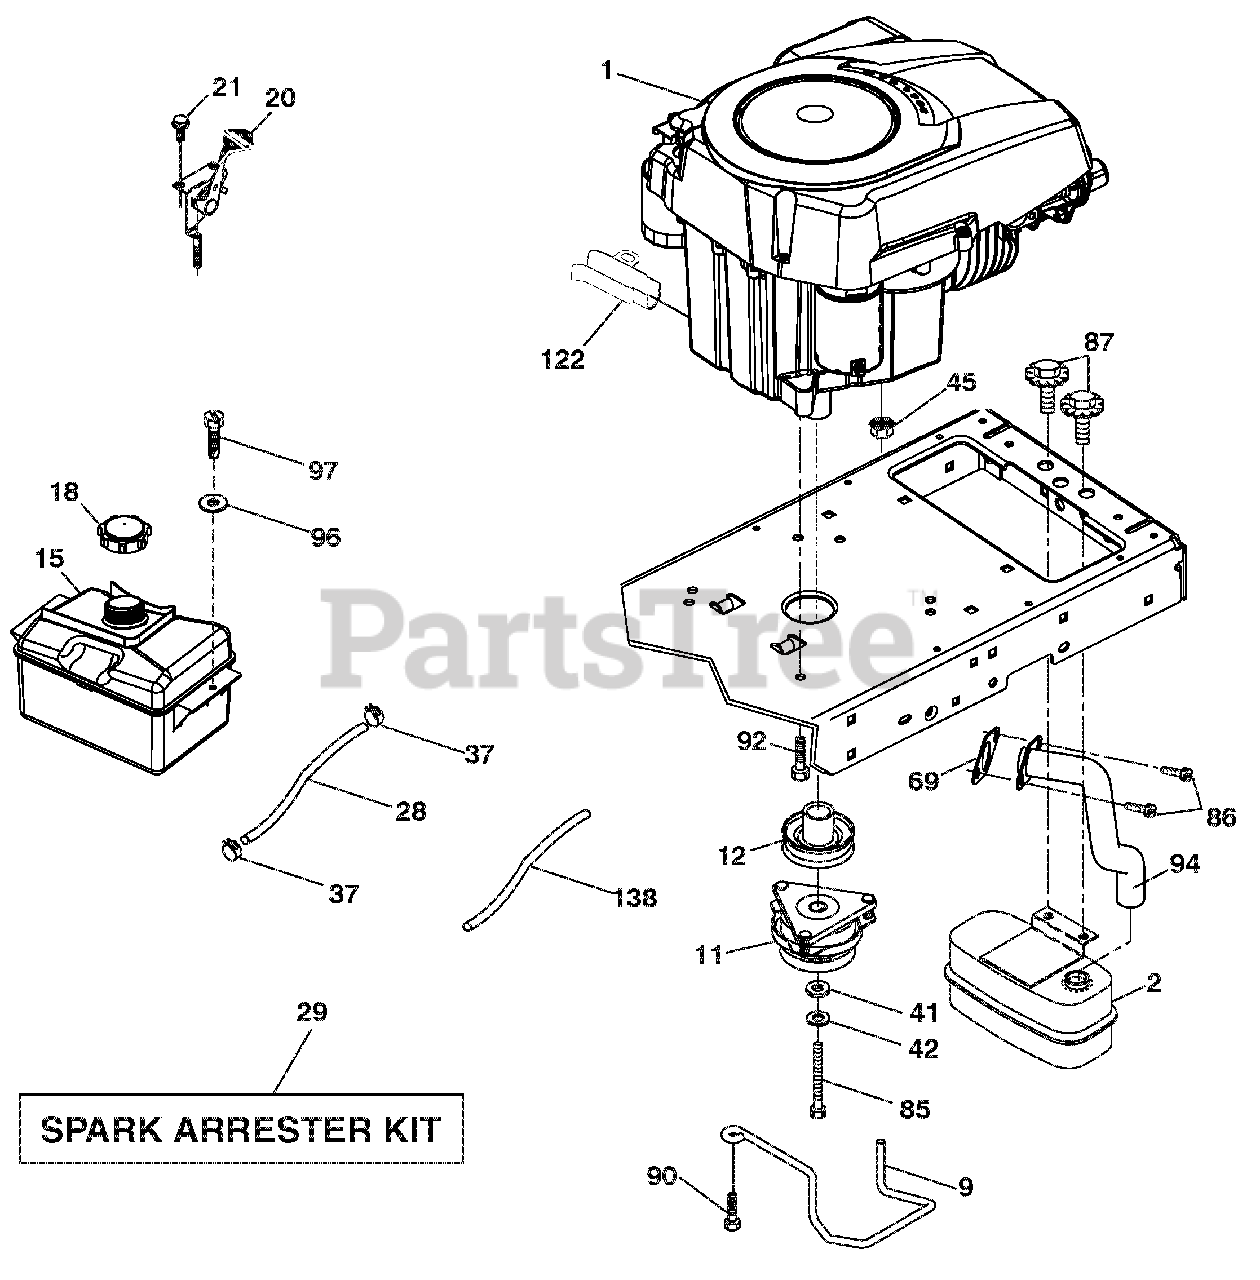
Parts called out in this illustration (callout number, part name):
1	ENGINE KOHL MODEL NO. SV590-3230(445326) (ORDER PARTS FROM ENGINE MANUFACTURER)
2	MUFFLER.SINGLE.CYL.KOHL.COURAG
9	KEEPER.BELT.ENGINE.4.25"NSTG
11	CLUTCH OGURA
12	PULLEY.ENGINE.TUFFTORQE.1"CRK.
15	TANK.FUEL.2.5.GAL.
18	CAP FUEL
20	CONTROL THROTTLE/CHOKE
28	LINE.FUEL.22"FRONT.EMIS.CA.LP
29	KIT.SPARK ARRESTOR(392390 B&S)
37	CLAMP.HOSE.BLK.
41	WASHER.1-1/2 ODX15/32 IDX.250
42	WASHER.LOCK.HVY HLCL.SPR.7/16
45	Nut, Keps Hex 1/4-20 unc
69	GASKET.KOHLER.SV.I.
85	BOLT.HEX.7/16-20X4XGR5-1.5THR.
86	SCREW SOCKET HEAD 5/16-18 X 1
87	BOLT.5/16-18 UNC X 1 W/SEMS.BL
90	SCREW.3/8-16X1.SMGML.TAP/R.BLK
92	SCREW.3/8-16 X 1.SMGML.TAP/R
94	TUBE.EXHAUST.KOHL.COURAGE
96	WASHER.9/32 X 7/8 X 16GA.
97	SCREW.HEXWSH.THDROL.1/4-20X3/4
122	Extension Drain Oil
138	PURGE.LINE.CARB
